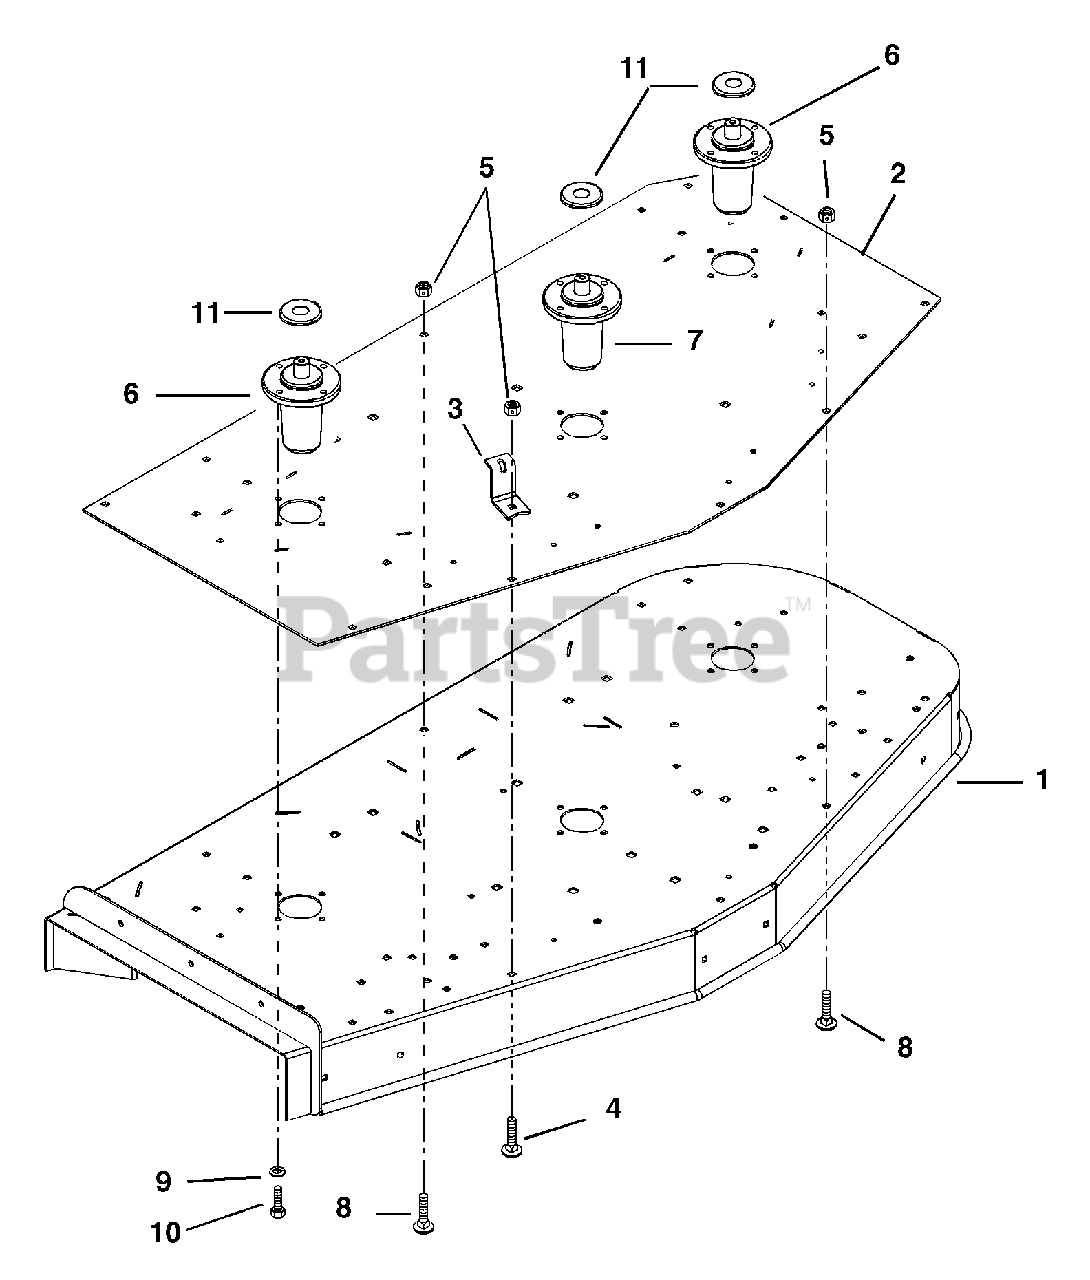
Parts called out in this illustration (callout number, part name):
1	Weldment, 60" Deck
2	Plate, 60" Reinforcing
3	Spring, Bracket
4	Bolt-Round Head Square Neck .38 - 16 x 1.25 Grade 2
5	Nut-Locking-Nylon .38 - 16
6	Assembly, Spindle L-Hub
7	Spindle Assembly (Center)
8	Bolt-Round Head Square Neck .38 - 16 x 1.00 Grade 2
9	Washer-Locking .38 x .094
10	Bolt-Hex .38 - 16 x 1.00 Grade 5
11	Slinger-Dust
